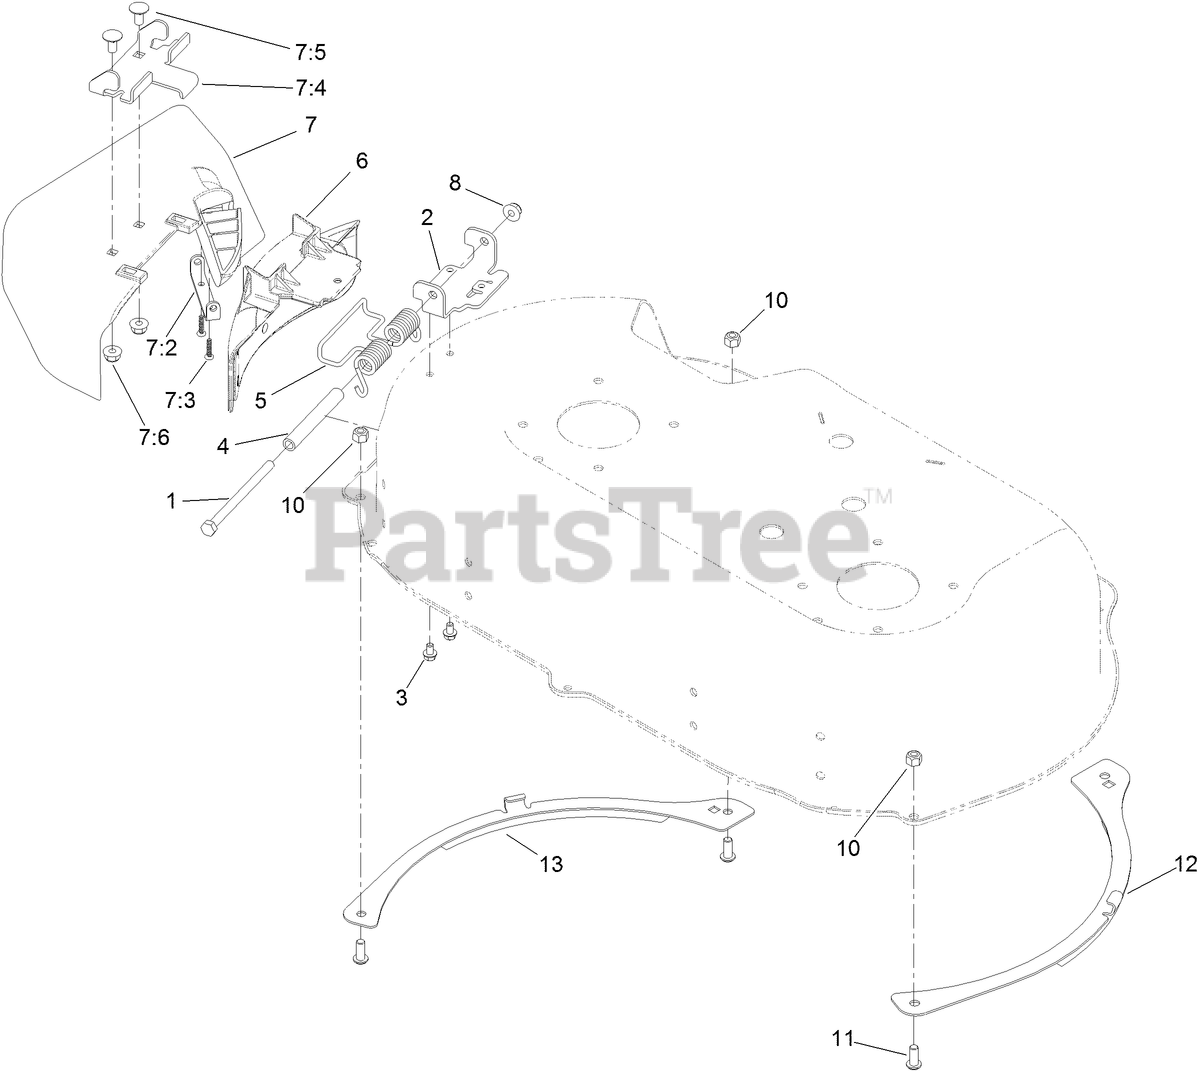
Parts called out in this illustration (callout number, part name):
1	SCREW-HH
3	SCREW-HWH
4	SPACER
5	SPRING-TORSION
6	COVER-DISCHARGE
7	SIDE DISCHARGE CHUTE ASM
7:2	BRACKET-COVER
7:3	SCREW-PPH
7:4	BRACKET-CHUTE
7:5	SCREW-CARR
7:6	NUT-HF, NI
8	NUT-HF, NI
10	NUT-LOCK, NI
11	SCREW-HSBH
